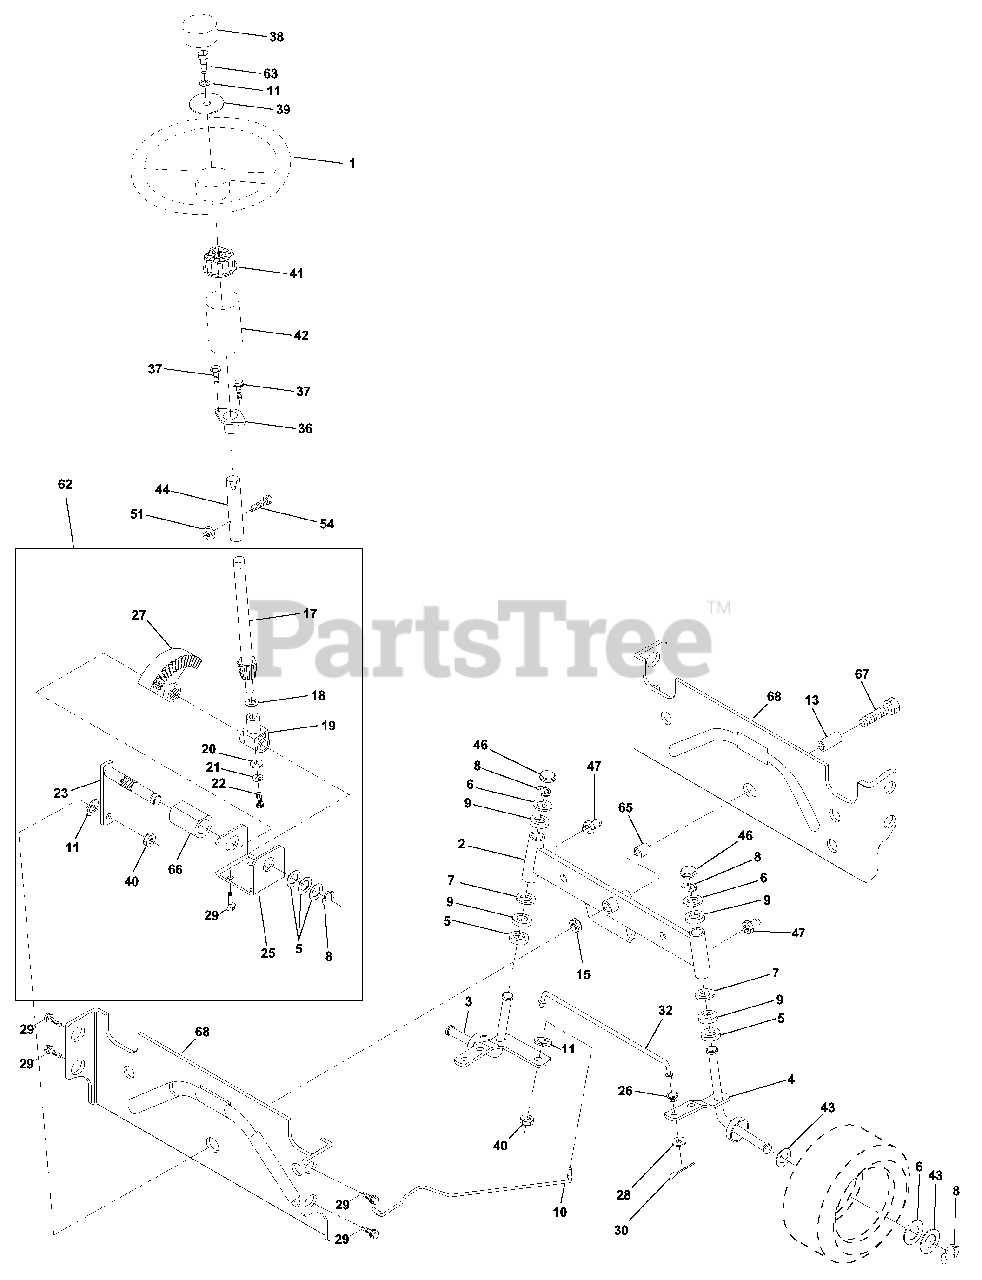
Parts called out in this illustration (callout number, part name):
1	Wheel Steering
2	Axle Asm STMP Dropped STL
3	Spindle Asm LH
4	Spindle Asm RH
5	Bearing Race Thrust Harden
6	Washer 25/32 X 1-5/8 X 16 Ga
7	Washer 27/32 X 1-1/4 X 16 Ga
8	Ring Klip #t5304-75
9	Bearing Col Strg Blk
10	Link Drag Extended Stamp
11	Washer Lock Hvy Hlcl Spr 3/8
13	Bearing Axle STLT/GT
15	Nut Lock Flange 5/8-11 Unc
17	Shaft Asm Strg
18	Washer Thrust 515x 750x 033
19	Support Shaft
20	Washer Shim 1/4 X 5/8 X 062
21	Washer Lock Hvy Helical 1/4
22	Screw Cap Sckt Hd Phos & Oil
23	Shaft Asm Pittman
25	Bracket Steering
26	Bushing Link Drag Blk LR
27	Gear Sector
28	Washer 13/32 X 7/8 X 16 Ga
29	Screw Thdrol 3/8-16x3/4 Ty-tt
30	Pin Cotter 1/8 X 3/4 Cad
32	Rod Tie Wire Form 19 75 Mech
36	Bushing Strg
38	Insert Cap Strg Wh Au
39	Washer 13/32 X 2-3/8 X 8 Ga
40	Lock nut
41	Adaptor Wheel Strg
42	Boot Steering Shaft
43	Washer 25/32 X 1 1/4 X 16 Ga
44	Extension Steering Shaft LR/LT
46	Cap Spindle Fr Top Blk
47	Fitting Grease
51	Nut Lock Hex w/Ins 5/16-18
54	Bolt Fin Hex 5/16-18 Unc x 1-1/4
62	Kit, Steering Assembly Svc
63	Bolt Fin Hex 3/8-16unc x 1 Gr. 5
65	Spacer Axle
66	Bearing Arm Pittman
67	Bolt, Fin Hex 5/8-11 UNC x 2-3/4
68	Axle, Brace
